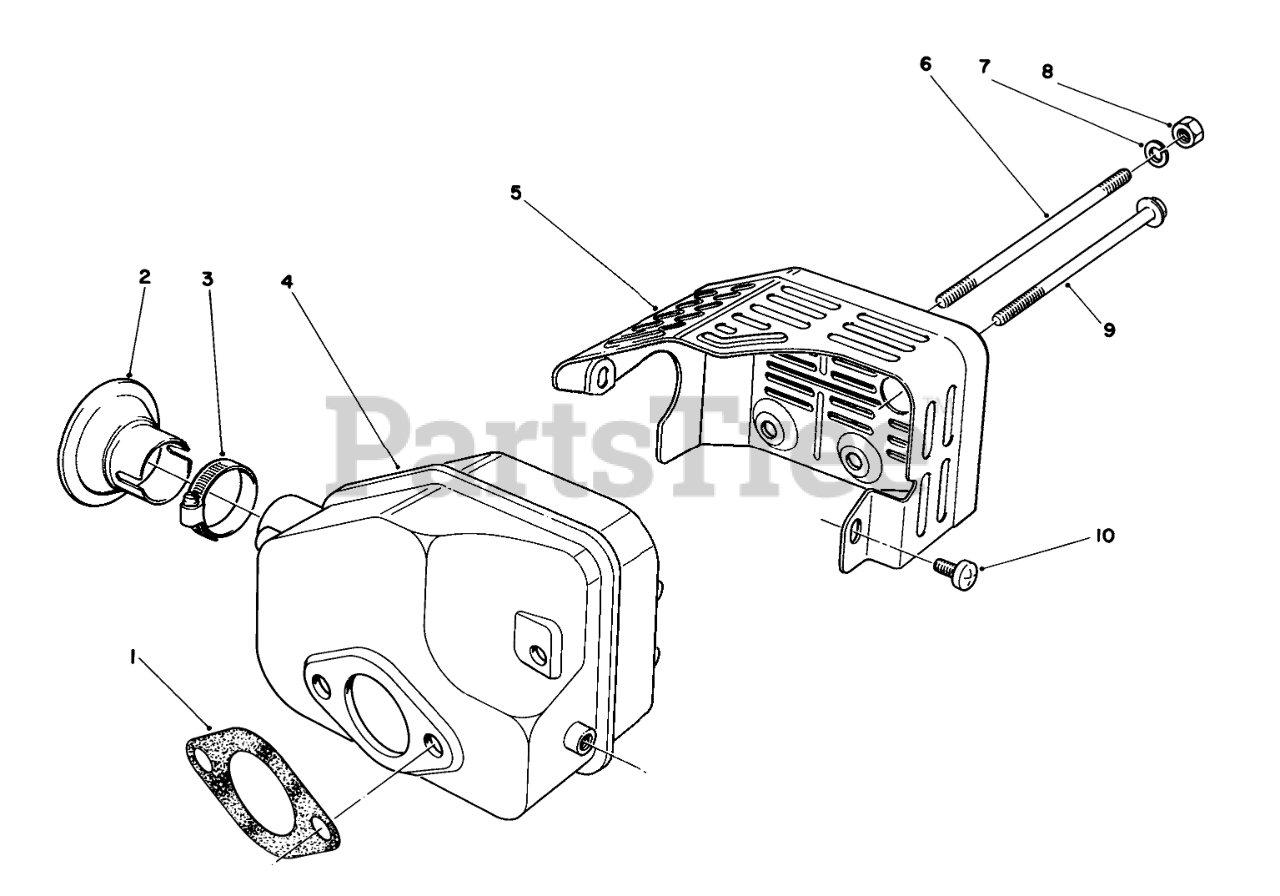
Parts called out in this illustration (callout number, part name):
1	GASKET
2	Arrestor-Spark
3	Clamp
4	Muffler
5	COVER
7	WASHER-LOCK
10	SCREW
